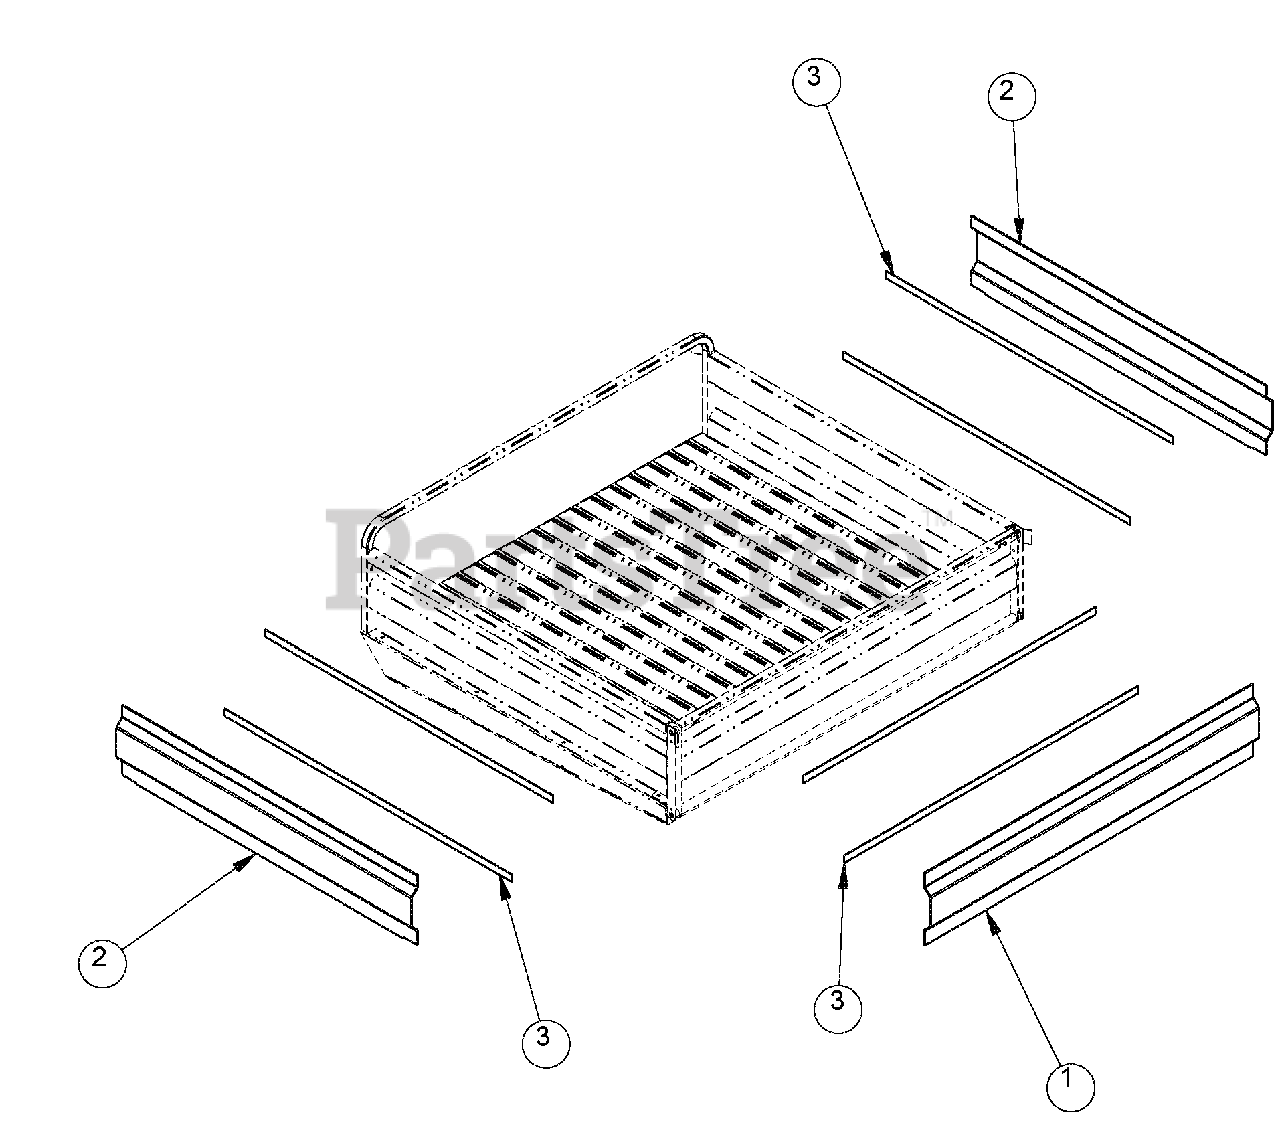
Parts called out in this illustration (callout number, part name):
1	PANEL, TAILGATE CAMO
2	PANEL, SIDE CAMO
3	TAPE, DOUBLE-SIDED
